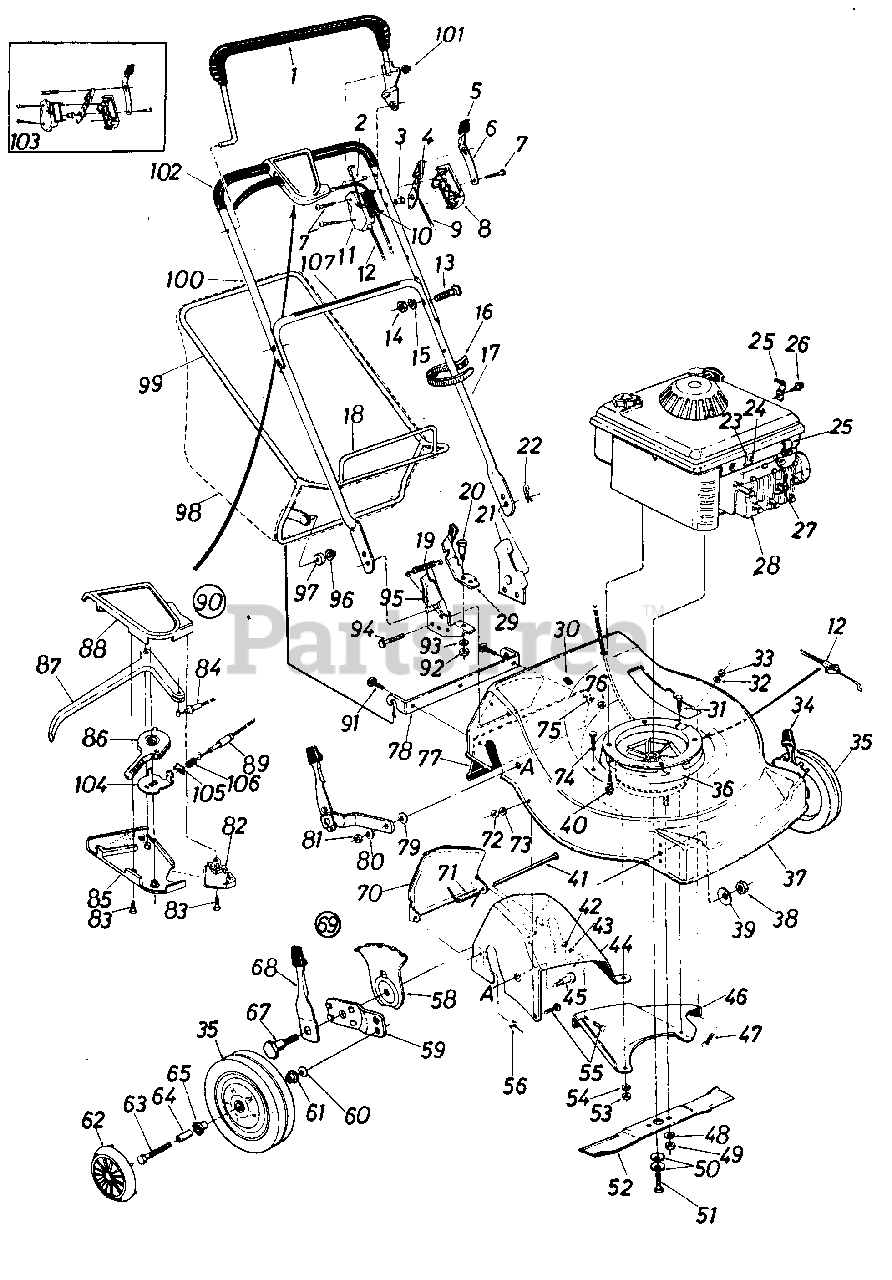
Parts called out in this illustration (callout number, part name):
1	L.H. Bail Ass'y.
3	Control Disc Pin
4	Throttle Control Lever
5	Spring Lever Knob
6	Lockout Spring
7	Truss Mach. Hi-B Tap Scr. #12 x 1.50" Lg.
8	Control Panel Half
9	Throttle Control Wire 58"
10	Control Label
11	Clutch Panel Half
12	Clutch Cable 46" Lg.
13	Carr. Bolt 5/16-18 x 1.38"
14	Hex Nut 5/16-18 Thd.*
15	L-Wash 5/16" I.D.*
16	Cable Tie
17	Lower Handle (Chrome)
20	Shld. Bolt .437" Dia. x .162
21	Handle Brkt. Ass'y. L.H.
22	Hairpin Cotter 5/16" Dia.
23	Hex B-Tap Scr. #10 x .62"
24	Casing Clamp
25	Cable Clip
26	Hex B-Tap Scr. #10 x .38"
27	Spark Plug Insulator
28	Engine
29	Catcher Lock Lever w/ Knob
31	Hex TT-Tap Scr. 1/4-20 x .75" Lg.
32	L-Wash. 1/4" I.D.*
33	Hex Nut 1/4-20 Thd.*
34	Height Adj. Ass'y. L.H.
35	Front Wheel Ass'y. Comp.
36	Blade/Brake Clutch Ass'y. Comp.
39	Bell-Wash. .39" I.D. x 1.13"
40	Hex Wash. Hd. TT-Tap Scr. 3/8-16 x 1.0" Lg.
42	Hex Nut 1/4-20 Thd.*
43	L-Wash. 1/4" I.D.*
44	Rear Chute R.H.
45	Shld. Bolt.500" Dia.
46	Rear Baffle L.H.
47	Carr. Bolt 1/4-20 x .50" Lg.*
48	L-Wash. 3/8" I.D.*
49	Hex Nut 3/8-24 Thd. Gr. 8
50	Bell-Wash. .40" I.D. x .88"
51	Hex Cl-Bolt 3/8-24 x 2.0" Lg. (Grade 8)
53	Hex Nut 1/4-20 Thd.*
54	L-Wash. 1/4" I.D.*
55	Carr. Bolt 1/4-20 x .50" Lg.*
56	Hex Sems Nut 1/4-20 Thd.
58	Height Adj. Plate
59	Wheel Pivot Bar
60	Bell-Wash. .40" I.D. x .88"
62	Plastic Hub Cap
65	Bearing
67	Shld. Bolt .50" Dia. x .430
68	Spring Lever Ass'y. w/ Knob
69	Height Adj. Ass'y. R.H.
70	Chute Door
71	Torsion Spring
72	Hex Nut 1/4-20 Thd.
73	L-Wash. 1/4" I.D.*
74	Hex Bolt 1/4-20 x .88" Lg.
75	Fl-Wash. .285" I.D. x 1.25"
76	Hex Sems Nut 1/4-20 Thd.
78	Grass Catcher Hitch Brkt.
79	Bell-Wash. .40" I.D. x 1.13"
80	Bell-Wash. .40" I.D. x .88"
81	Hex Jam Nut 3/8-16 Thd.
82	Cable Mounting Cap
83	Flat "C" Sunk Hd. Tap Scr. #10 x .75" Lg.
84	S.P. Cable 53" Lg.
85	3-Sp. S.P. Control Lower Cover
86	Shimano 3-Sp. Shift Lever
87	Control Lever
88	3-Sp. S.P. Control Upper Cover
89	Shimano 3-Sp. Solid Shift Cable
90	Clutch Control Hsg. Comp.
91	Carr. Bolt 1/4-20 x .75" Lg.
92	Hex Nut 5/16-18 Thd.
93	L-Wash. 5/16" I.D.*
94	Hex L-Wash. Hd. AB-Tap Scr. 1/4" x .62" Lg.
95	Handle Brkt. Ass'y. R.H.
96	Push Nut 3/8" Rod
97	Plastic Roller
99	Catcher Upper Frame
100	Upper Handle (Chrome)
102	Grip
103	Control Housing Comp.
104	Shimano 3-Sp. Shift Lever Brkt.
105	Shimano 3-Sp. Cable Spring Brkt.
106	Shimano 3-Sp. Cable Mounting Spring
107	Instruction Label
8365-000-6	Hardware Pack
